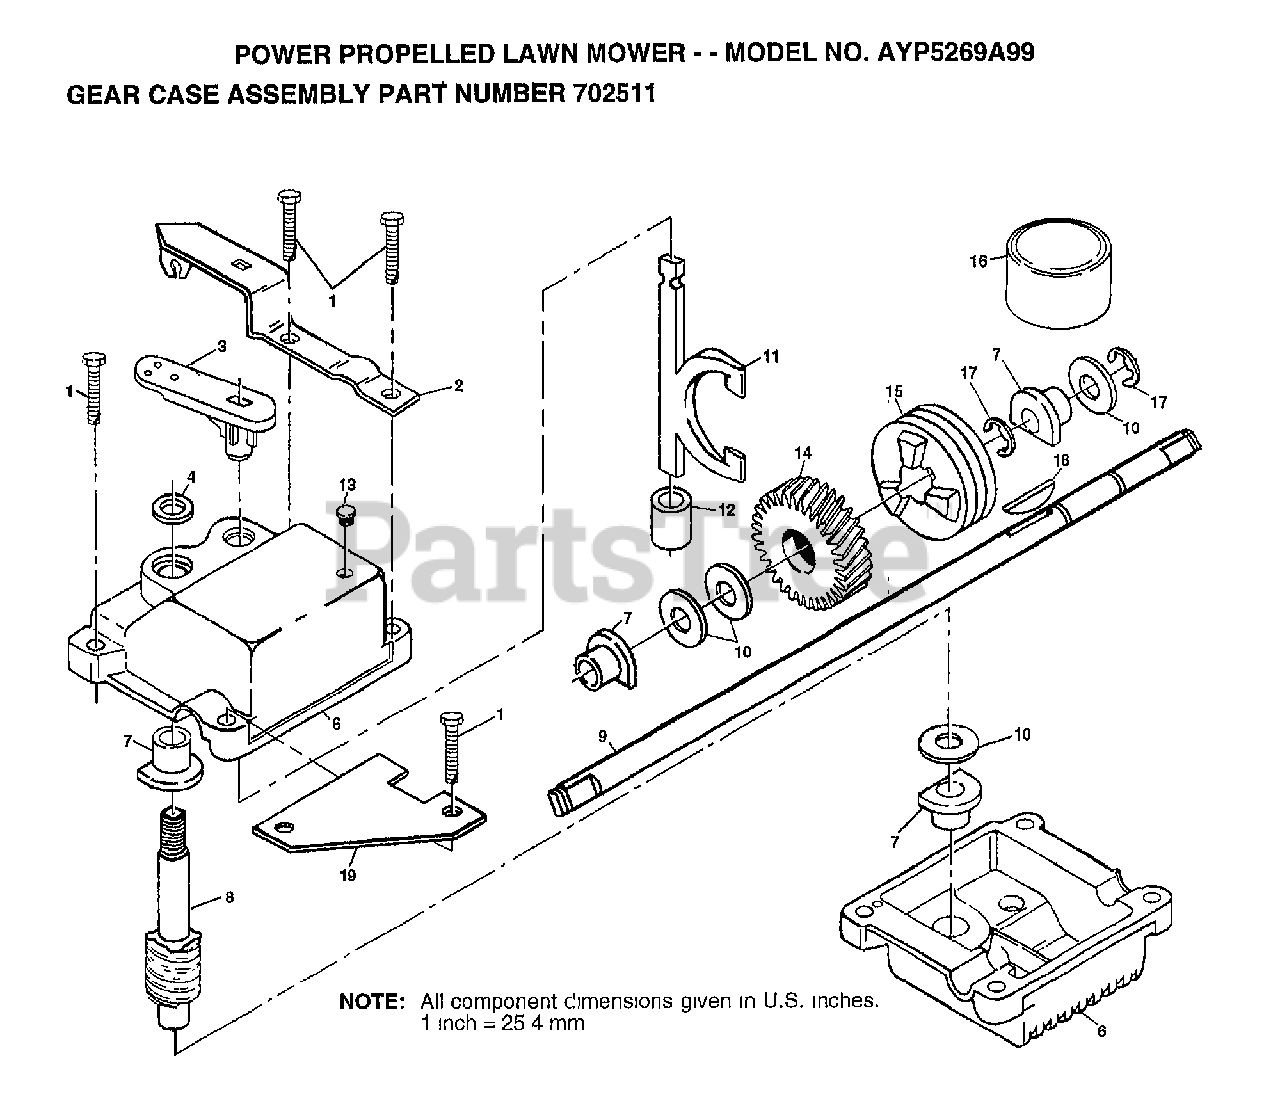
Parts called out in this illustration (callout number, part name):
1	SCREW.1/4-20
2	BRACKET.GEARCASE
3	SHIFTER
4	SEAL
6	KIT GEARCASE HALV
7	BEARING
8	SHAFT.WORM
9	SHAFT.DRIVE
10	THRUST WASHER
11	CLUTCH YOKE
12	BUSHING.GEAR BOX
13	PLUG PM
14	GEAR.HELICAL
15	CLUTCH JAW
17	RING T
18	HI PRO KEY
